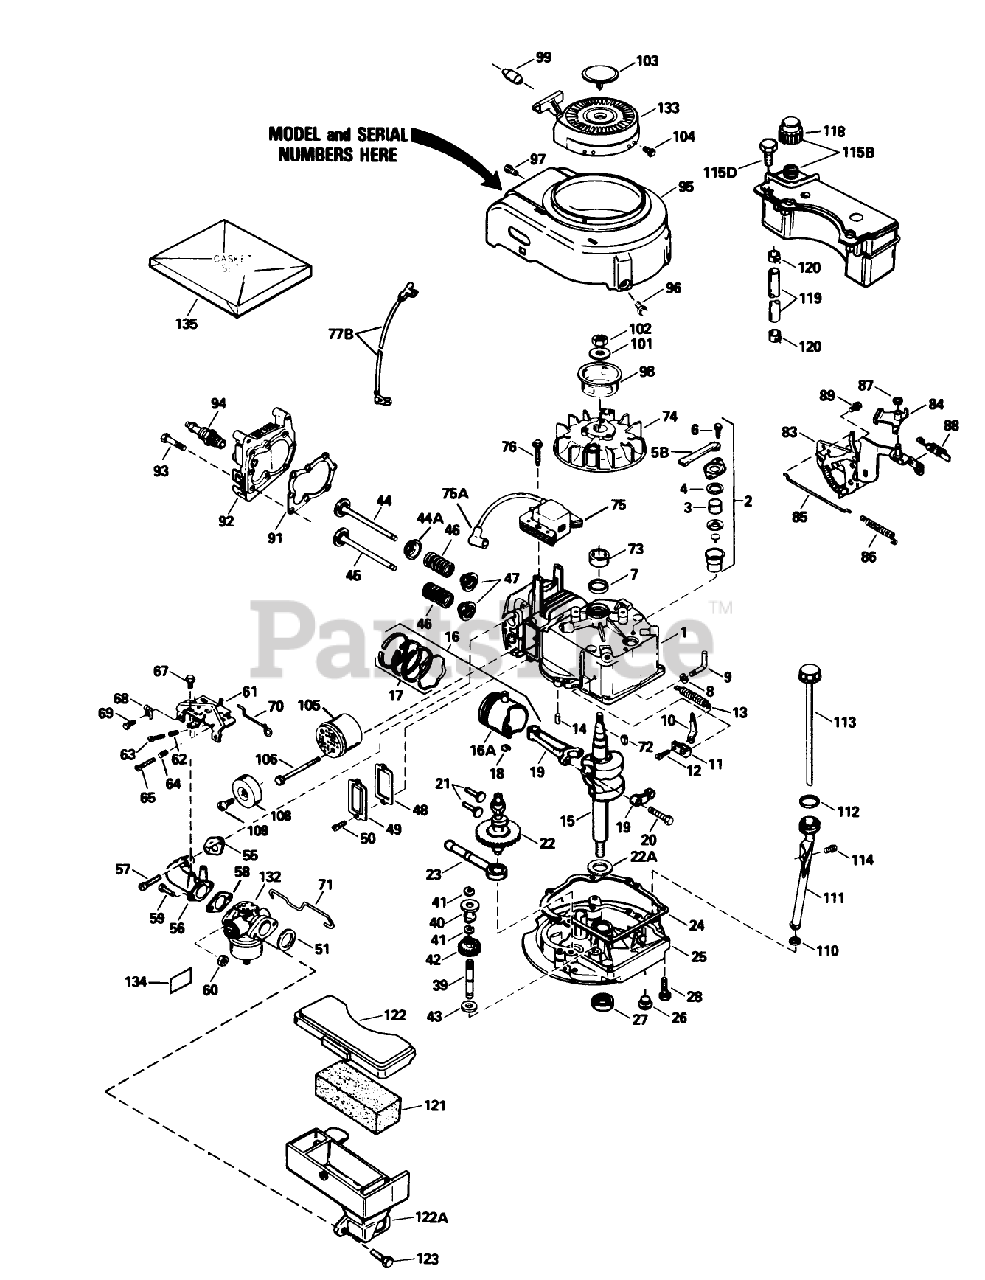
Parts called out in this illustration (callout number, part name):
1	Cylinder Assy. (Incl. #24)
2	Breather Assy. (Incl. Ref. #46 thru 51)
3	Element-Breather
4	Gasket-Breather
5B	Tube, Breaker
6	Screw (10-24 x 9/16)
7	Seal-Oil
8	Washer-Flat
9	Rod, Governor (Incl. No. 36)
10	Governor Lever
11	Clamp-Lever, Governor
12	Screw
13	Spring Governor
14	Pin-Dowel
15	Crankshaft
16	Piston-Pin Ring Assy. (Std.)(Incl. Ref. #16A, 17 18)
16	Piston-Pin Ring Assembly (.010 oversize)(Incl. Ref. #16A, 17 18)
16	Piston, Pin Ring Assy. (.020 Oversize)(Incl. Ref. #13A, 14, 15)
16A	Piston Pin Assy. (Std.)(Incl. Ref. #14)
16A	Piston Pin Assembly (.010 oversize)(Incl. Ref. #18)
16A	Piston Pin Assy. (.020 Oversize) (Incl. Ref. #14)
17	Ring Set-Piston (Std.)
17	Ring Set, Piston(.0100versize)
17	Ring Set (.020" OS)
18	Ring-Retaining, Piston Pin
19	Rod Assy., Connecting (Incl. Ref. #17)
20	Bolt-Rod, Connecting
21	Lifter-Valve
22	Camshaft(Mech.Comp. Release)
22A	Washer-Thrust
23	Oil Pump ASM
24	Gasket
25	Flange-Mounting (Incl. Ref. #26, 27 39)
26	Plug Oil Drain
27	Seal-Oil
28	Screw (1/4-20 x 1-1/4)
39	Shaft-Governor
40	Spool-Governor
41	Ring-Retaining
42	Governor Gear ASM
43	Washer
44	Valve, Intake (Std.) (Incl. Ref. #40)
44	Valve, Intake (1/32" oversize)(Incl. No. 40)
44A	Seal Assy., Intake
45	Valve, Exhaust (Std.)(Incl. No. 40)
45	Valve, Intake (1/32" oversize)(Incl. No. 40)
46	Spring-Valve
47	Cap-Valve, Spring
48	Gasket-Cover, Valve
49	Cover-Valve
50	Screw
51	Gasket-Cleaner, Air
55	Gasket-Intake Pipe
56	Pipe-Intake (Incl. Ref. #59)
57	Screw (1/4-20 x 1)
58	Gasket
60	Nut and Lock Washer (1/4-28)
61	Control Assy.-Remote Speed (Incl. Ref. #69 thru 72 76)
62	61709/GIL1515A/95-5
63	Screw
64	Spring-Compression
65	Screw
67	Screw (10-24 x 9/16)
68	Conduit
69	Screw (10-32 x 3/8)
70	2035A67 ADD.ASSEMBL
71	Link-Throttle
72	Key-Flywheel
73	Spacer
74	Flywheel
75	Solid State
75A	Cover-Spark Plug
76	Screw
77B	Ground Wire
83	Bracket-S.E. Brake
84	Lever-Brake
85	Link-Control
86	Spring-Extension
87	Ring-Retaining
88	Terminal
89	Screw (1/4-20 x 3/8)
91	Gasket-Cylinder Head
92	Head-Cylinder
93	Screw (5/16-18x1-1/2)
94	Spark Plug-Resistor (R J19 L M)
95	Housing-Blower
96	Screw (1/4-20 x 1/2)
97	Screw (10-24 x 9/16)
98	Hub-Starter
99	Retainer-Starter Rope
101	Washer-Belleville
102	Nut-Flywheel
103	Plug Starter
104	Screw, Hex Hd.
105	Muffler (Incl. Ref. #122)
106	Screw
108	Cover-Muffler
109	Screw (8-32 x 3/8)
110	Gasket
111	Oil Fill Tube
112	O-Ring
113	Dipstick
114	Screw (10-32 x 1/2)
115B	Tank Assembly-Fuel (Incl. Ref. #102)
115D	Screw (10-32 x 35/64)
118	Cap-Fuel
119	Line-Fuel
120	Clamp-Line, Fuel
121	Filter-Air Cleaner
122	Cover-Air Cleaner
122A	Body Air cleaner
123	Screw
132	Carburetor (Incl. Ref. #83)
133	Starter-Rewind
134	Decal-Primer
135	Gasket Set (Incl. Items Marked *)
